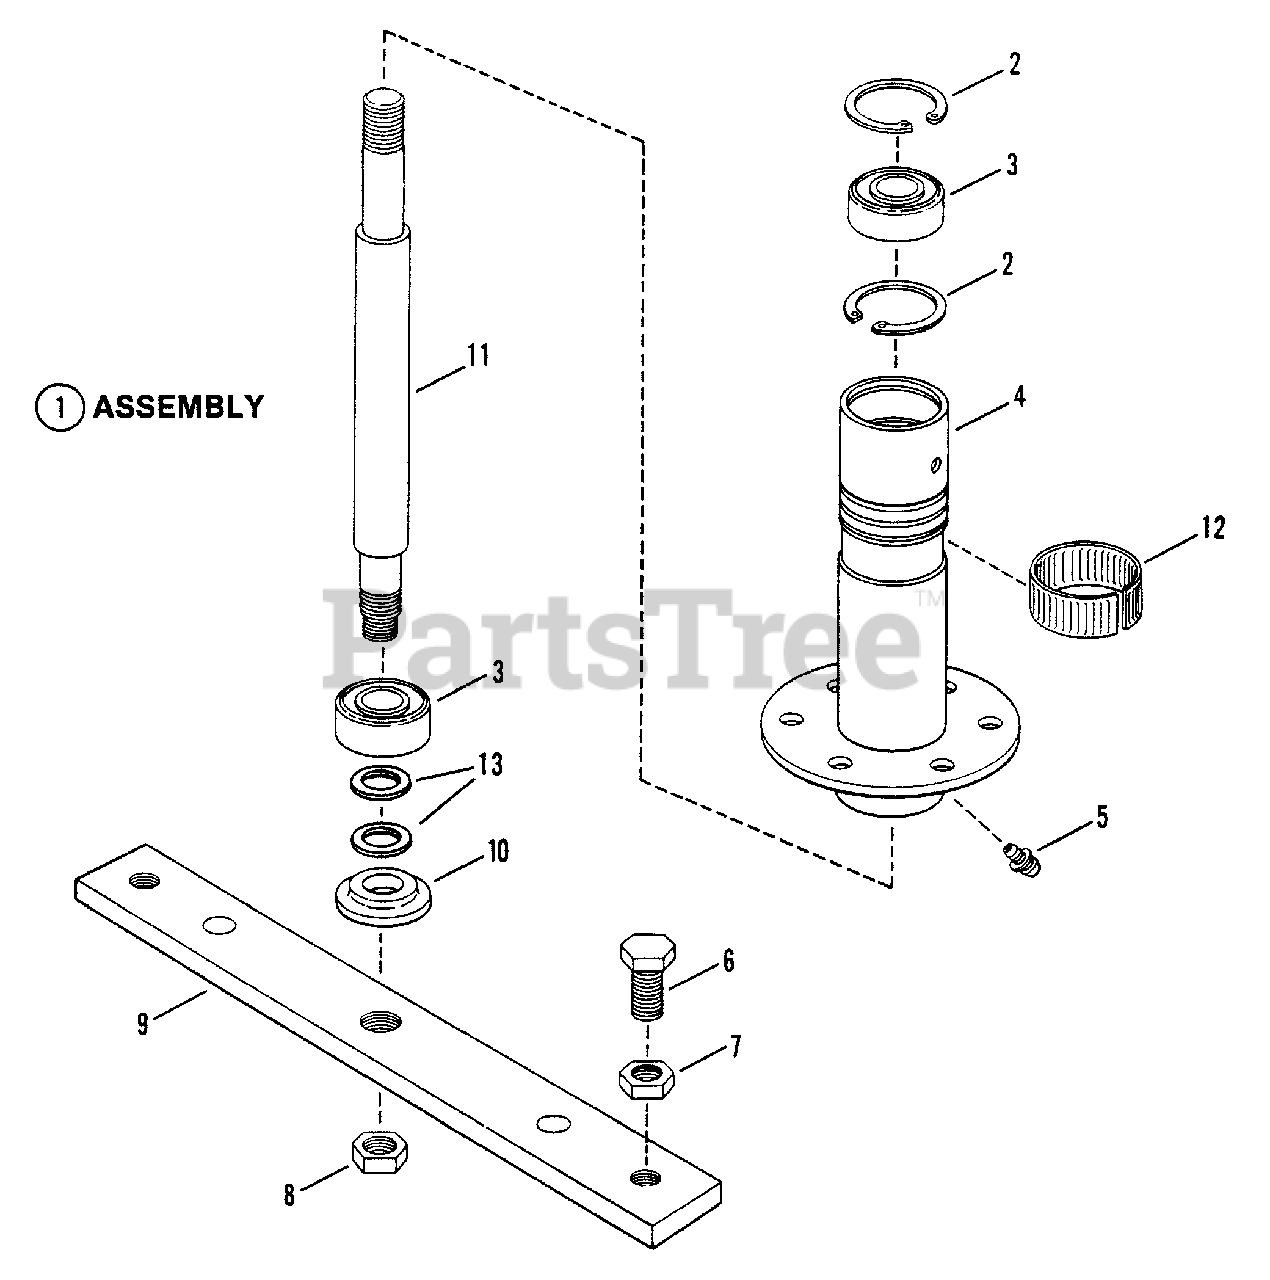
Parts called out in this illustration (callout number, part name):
1	ASSEMBLY, Spindle Housing
2	RING, Retaining
3	BEARING, Spindle
4	HOUSING, Spindle
5	FITTING, Lube (Press fit for .187 hole-no ball)
6	SCREW, 1/2-20 x 1" Hex Head Cap (GR. 5)
7	NUT, 1/2-20 Hex Jam
8	NUT, 5/8-18 Hex Lock
9	HOLDER, Blade
10	WASHER, Spindle
11	SPINDLE, Shaft (10.237" Long)
12	RING, Tolerance
13	WASHER, Shim
